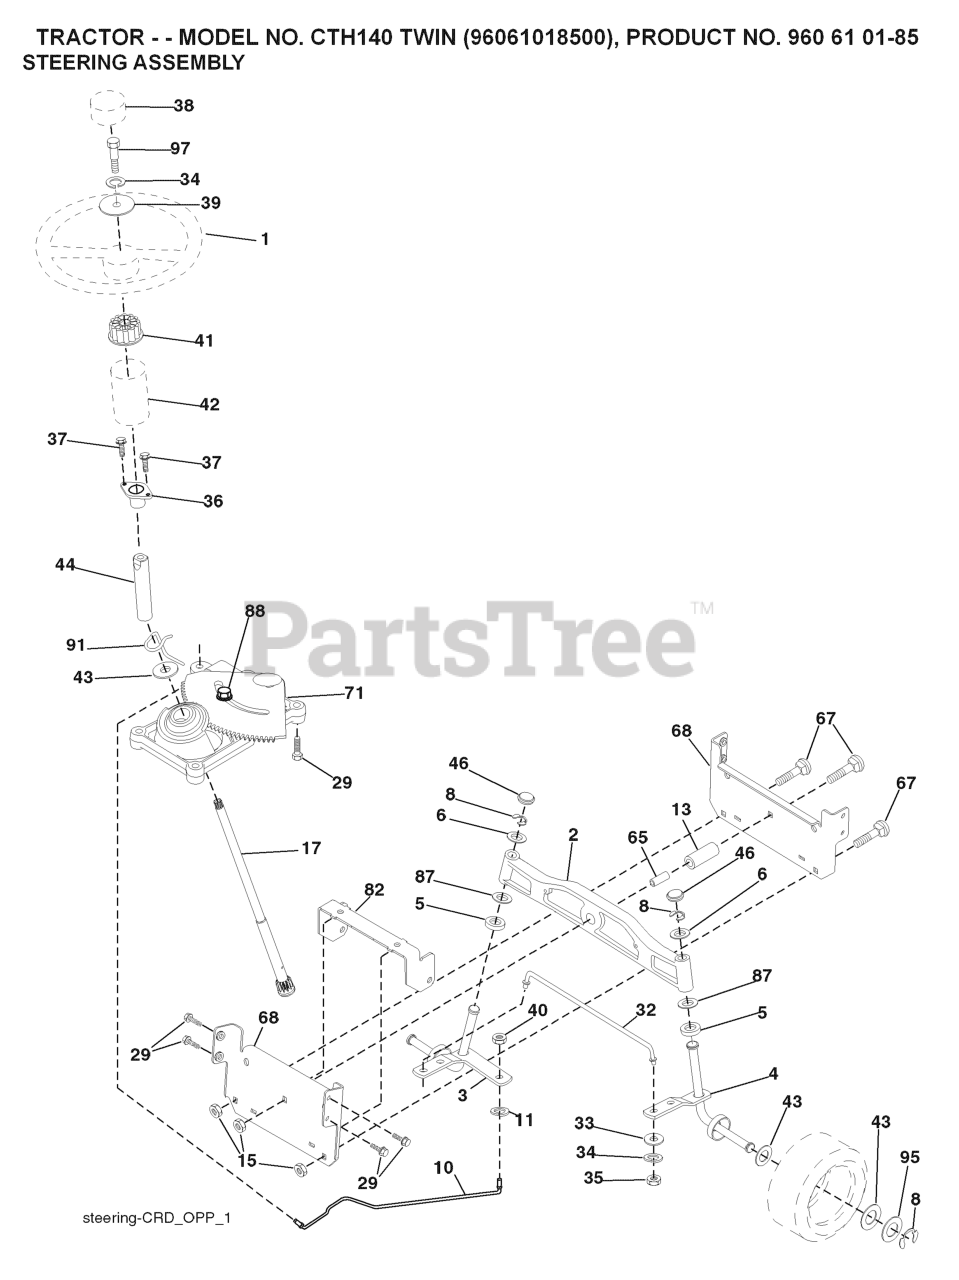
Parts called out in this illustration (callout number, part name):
1	STEERING WHEEL
2	AXLE ASSY FRONT
3	SPINDLE.ASM.LH.15"TIRES
4	SPINDLE.ASM.RH.15"TIRES
5	THRUST WASHER
10	DRAGLINK.15".TIRES.2001
11	WASHER, LOCK 3/8
13	TUBE, PIVOT AXLE
15	NUT
17	SHAFT STEERING SPLINE
29	SCREW, 3/8-16X3/4
33	WASHER M
34	WASHER.LOCK.HVY.HLCL.SPR.5/16
35	NUT, CROWNLOCK
36	BUSHING, STEERING
37	SCREW.TT.#10-32X.5.3/8.FLANGE
38	INSERT.CAP.STRG.WH.GRAY
39	WASHER.11/32
40	NUT CROWNLOCK 3/8-24
41	ADAPTER, WHEEL STNG..
42	BOOT, STEERING
44	SHAFT.EXTEN.STRG.SPLINE
46	CAP.SPINDLE.BLACK
65	SPACER BRACE AXLE
67	BOLT CARRIAGE
68	BRACE.AXLE.15"TIRES
71	STEERING ASM
82	BRACKET.SUSP.CHASSIS.FRONT.15
87	WASHER, FLAT .781 X 1 1/2"
88	BOLT, SHOULDER 7/16-20
91	CLIP.STEERING
95	WASHER.HARDENED
